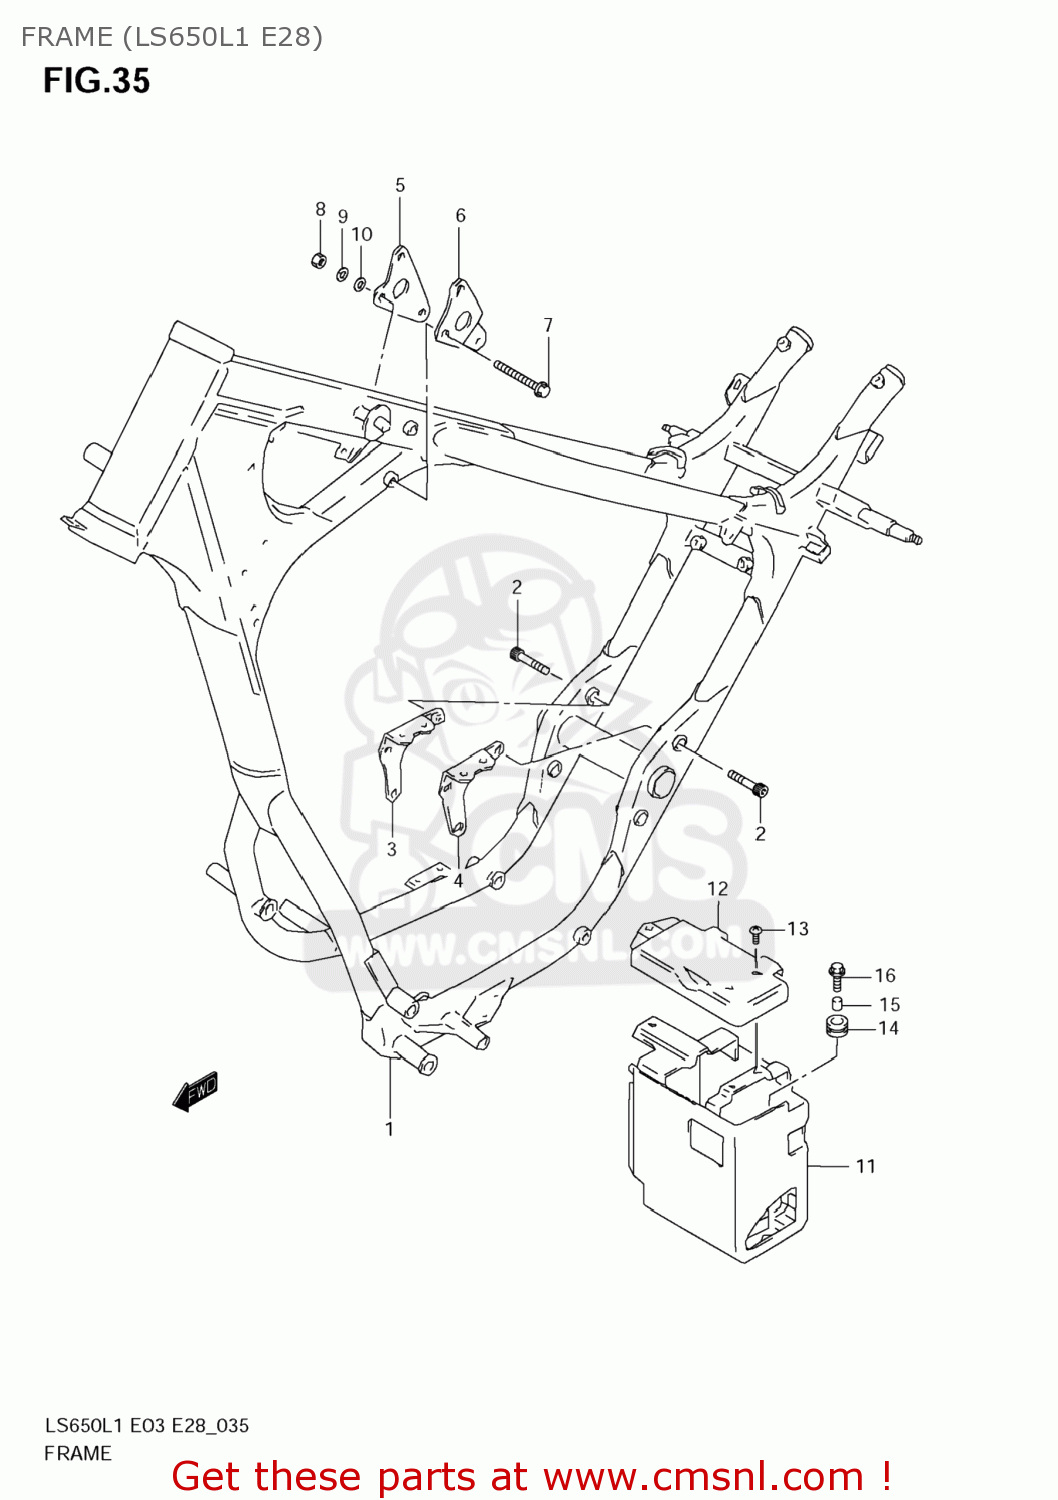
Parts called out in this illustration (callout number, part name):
1	FRAME(BLACK)
2	BOLT(8X40)
3	PLATE,ENGINE MOUNT NO.4,R
4	PLATE,ENGINE MOUNT NO.4,L
5	PLATE,ENGINE MOUNT NO.5,R
6	PLATE,ENGINE MOUNT NO.5,L
7	BOLT(8X72)
8	NUT
9	WASHER,LOCK
10	WASHER
11	HOLDER,BATTERY
12	COVER,BATTERY
13	SCREW
14	CUSHION
15	SPACER(6.5X9X7.2)
16	BOLT(6X20)
